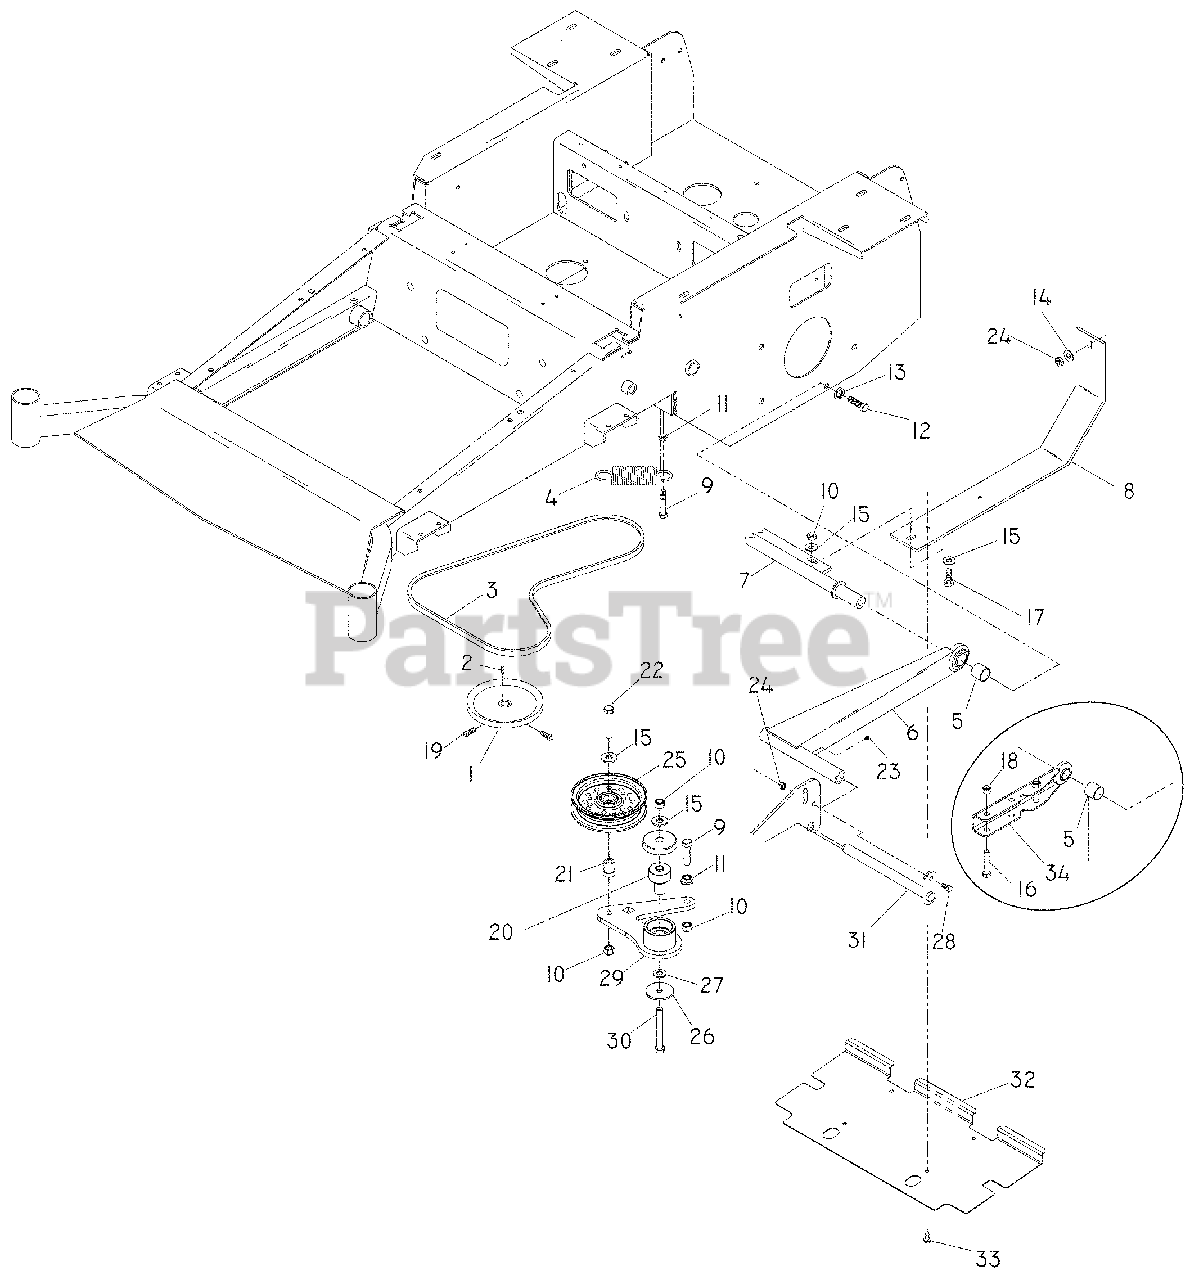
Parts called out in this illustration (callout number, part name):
3	PUMP BELT
5	STRUT SPACER
6	STRUT WELDMENT, REAR 52"/61"
7	CROSS SHAFT
8	SKID PLATE
9	HCS 3/8-16 x 1½
10	NUT 3/8-16 HEX NYLOC
11	NUT 3/8-16 HEX WHIZLK
13	LOCKWASHER 7/16
14	WASHER, 5/16 STD FLT
15	WASHER 3/8 FLAT
16	HCS ½-13 x 3¼
17	HCS, 3/8 -16 x 1
18	NUT ½ -13, NYLOC
19	SCREW, SET
20	PIVOT BEARING
21	IDLER FLANGE BUSHING
22	HCS, 3/8-16 x 2
23	ZERK
24	NUT 5/16-18 HEX NYLOC
25	IDLER PULLEY
26	WASHER, 3/8 SPEC
27	WASHER, 3/8 SAE FLT
28	HCS 5/16-18 x 1
30	HCS 3/8-16 x 3
31	PIVOT PIN WELDMENT 52"/61"
32	GUARD, REAR DEBRIS MODELS 968999677, 968999751
33	BOLT 5/16-18 x ¾ THRD FRM MODELS 968999677, 968999751
34	STRUT WELDMENT, REAR MODELS 968999677, 968999751
